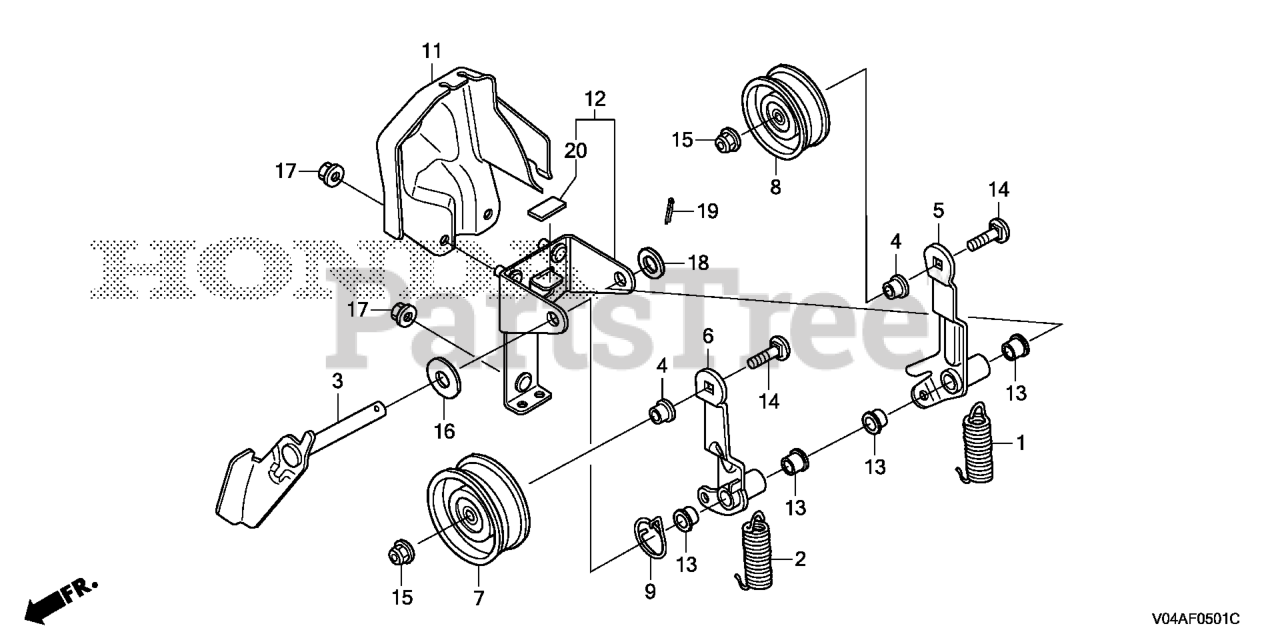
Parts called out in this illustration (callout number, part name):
1	SPRING, WHEEL TENSIONER RETURN
2	SPRING, AUGER TENSIONER RETURN
3	ARM, AUGER BRAKE
4	COLLAR, ROLLER
5	ARM, WHEEL TENSION
6	ARM, AUGER TENSIONER
7	ROLLER, TENSIONER
8	ROLLER, TENSIONER
9	SPRING, BRAKE ARM (NOT AVAILABLE)
11	HOLDER, WIRE
12	BRACKET, TENSION ARM
13	BUSH, CHANGE ARM
14	BOLT, CARRIAGE (8X28)
15	NUT, FLANGE (8MM)
16	WASHER, BRAKE ARM
17	NUT, FLANGE (8MM)
18	WASHER, PLAIN (12MM)
19	PIN, COTTER (3.0X18)
20	RUBBER, STOPPER
